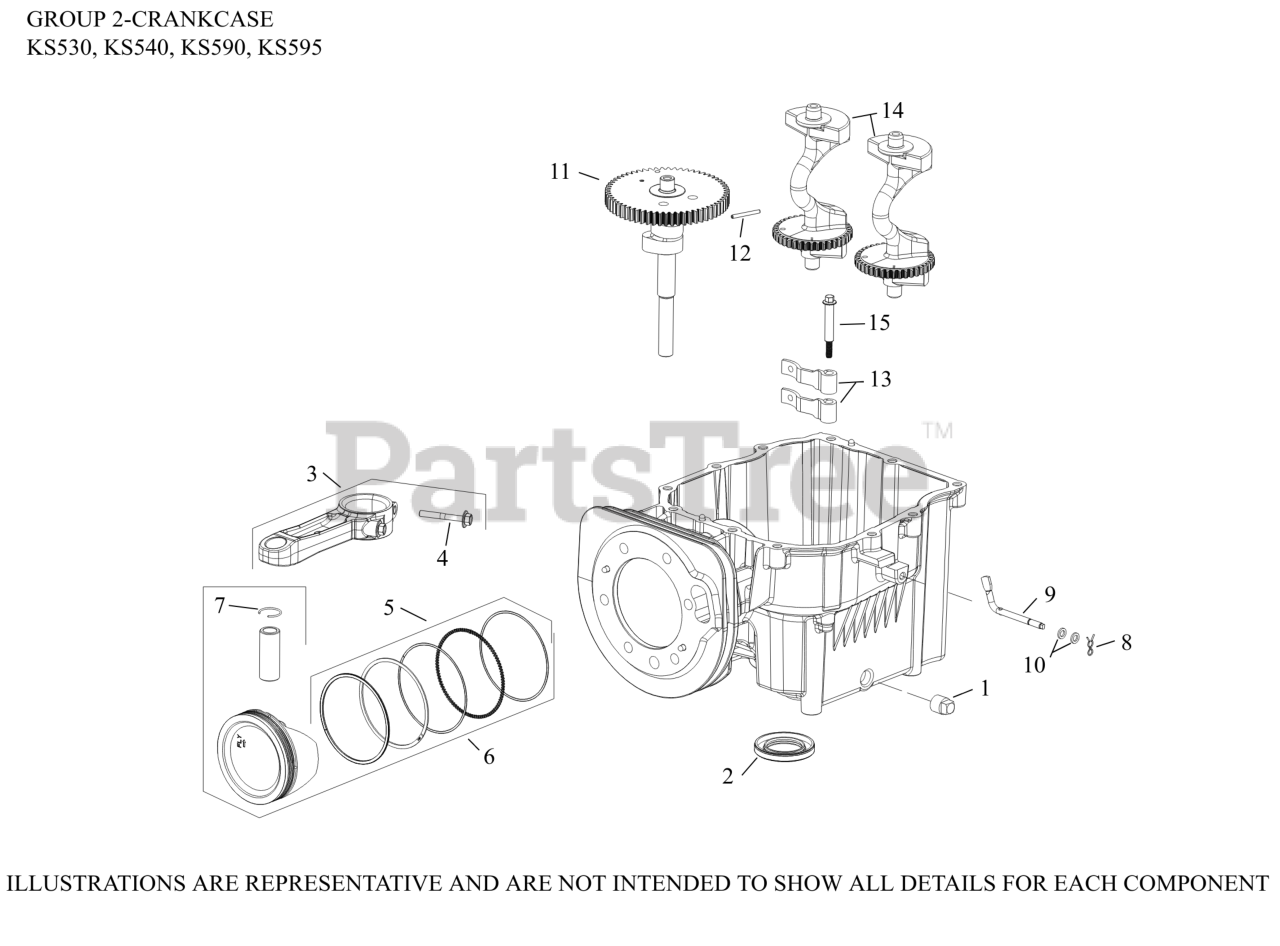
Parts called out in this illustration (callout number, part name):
1	PLUG, SQ HD PIPE 3/8"
2	SEAL, OIL
3	ROD, CONNECTING ASSEMBLY
4	SCREW, HEX FLANGE REDUCED BODY (M6 X 47)
5	RING SET (94MM)
6	KIT, PISTON, RINGS, PIN AND CLIPS
7	RETAINER, PISTON PIN
8	CLIP, HITCH PIN
9	SHAFT, GOVERNOR CROSS
10	WASHER, FLAT 6 MM
11	CAMSHAFT ASSEMBLY
13	LEVER, CAM
14	SHAFT, PRIMARY BALANCE
15	SCREW, HEX FLANGE SHOULDER (M6)
